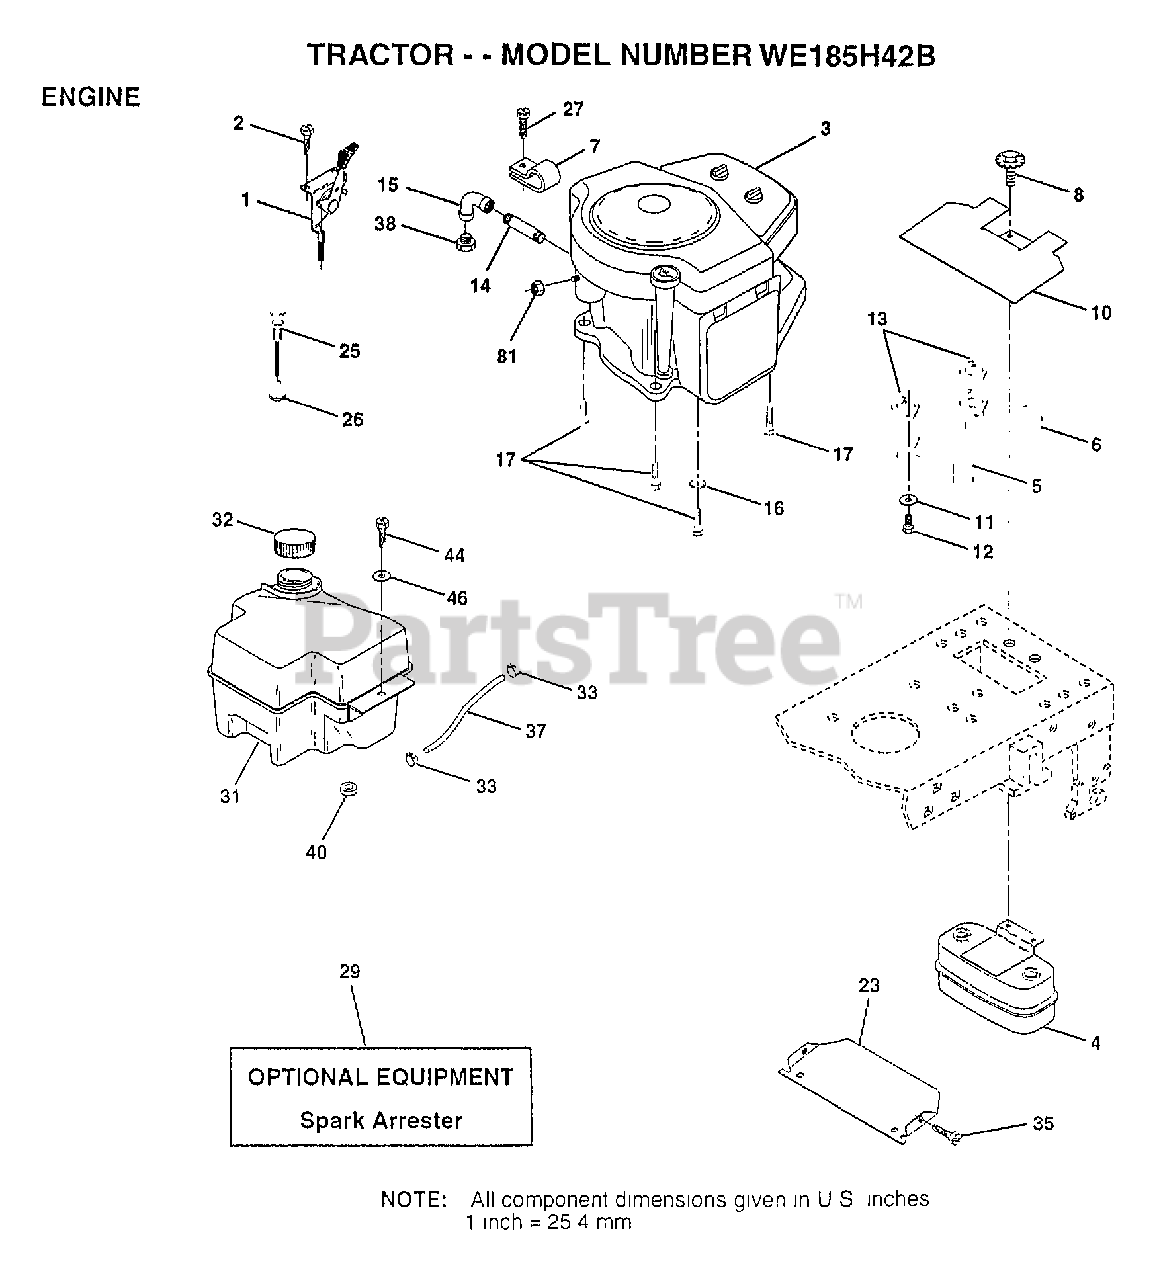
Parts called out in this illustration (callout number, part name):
1	CONTROL THRT 35.5
2	SCREW LT
3	ENGINE, BRIGGS
4	MUFFLER.TW.LOTONE
5	EXHAUST.B&S.18.LH
6	EXHAUST.B&S.18.RH
7	CLAMP.TUBE.DBL.EN
8	BOLT.5/16-18.UNC
10	SHIELD.HEAT.
11	LOCKWASHER
13	GASKET MUFFLER
14	PIPE NIPPLE LT
15	ELBOW
16	LOCKWASHER
17	SCREW LT
23	SHIELD-HEAT
25	CONTROL.CHOKE.37
26	"NUT,KEPS 3/8-24IM"
27	"SCREW-TT,10-32 FL"
32	CAP ASM FUEL
33	HOSE CLAMP
35	SCREW
37	LINE FUEL
44	SCREW HEX CRT
46	WASHER
81	NUT
